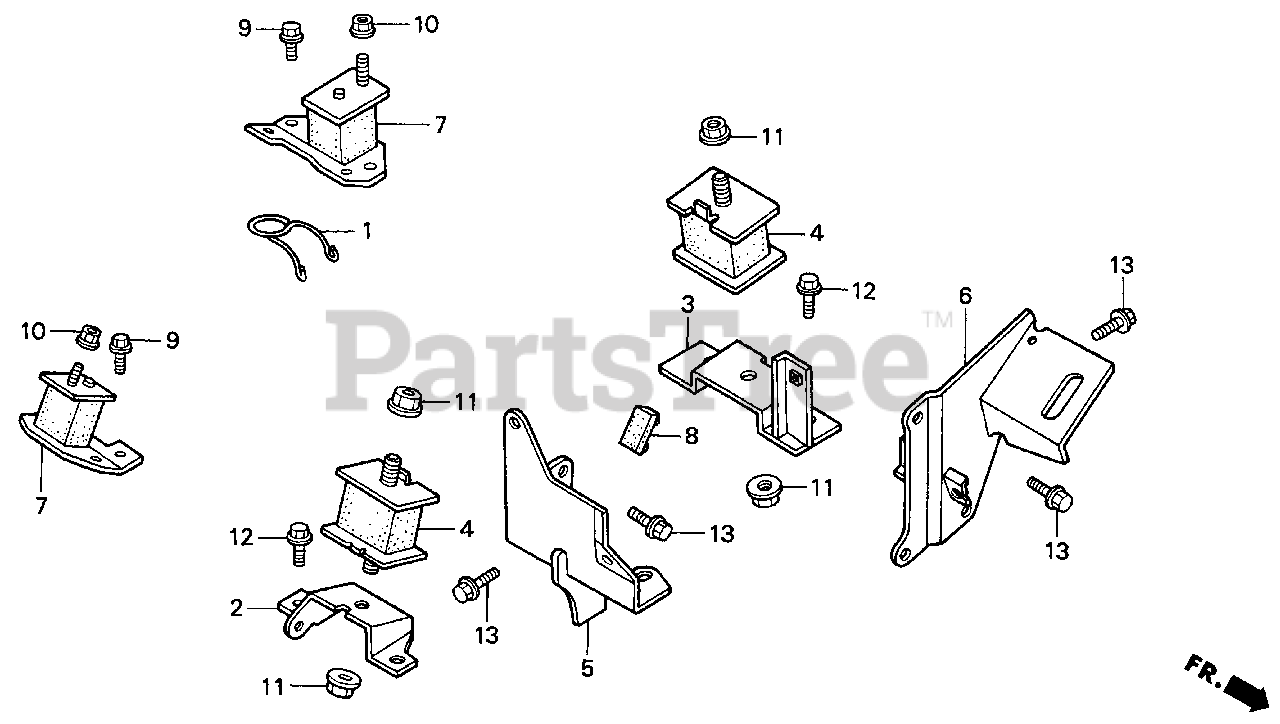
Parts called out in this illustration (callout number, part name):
1	GUIDE, WATER HOSE
2	PLATE A, ENGINE MOUNTING
3	PLATE B, ENGINE MOUNTING
4	RUBBER, ENGINE SETTING
5	BRACKET, R. FR. ENGINE MOUNTING
6	BRACKET, L. FR. ENGINE MOUNTING
7	RUBBER, ENGINE MOUNTING
8	RUBBER, ENGINE (LOWER)
9	BOLT, FLANGE (8X18)
10	NUT, FLANGE (8MM)
11	NUT, FLANGE (10MM)
12	BOLT, FLANGE (8X14)
13	BOLT, FLANGE (8X20)
